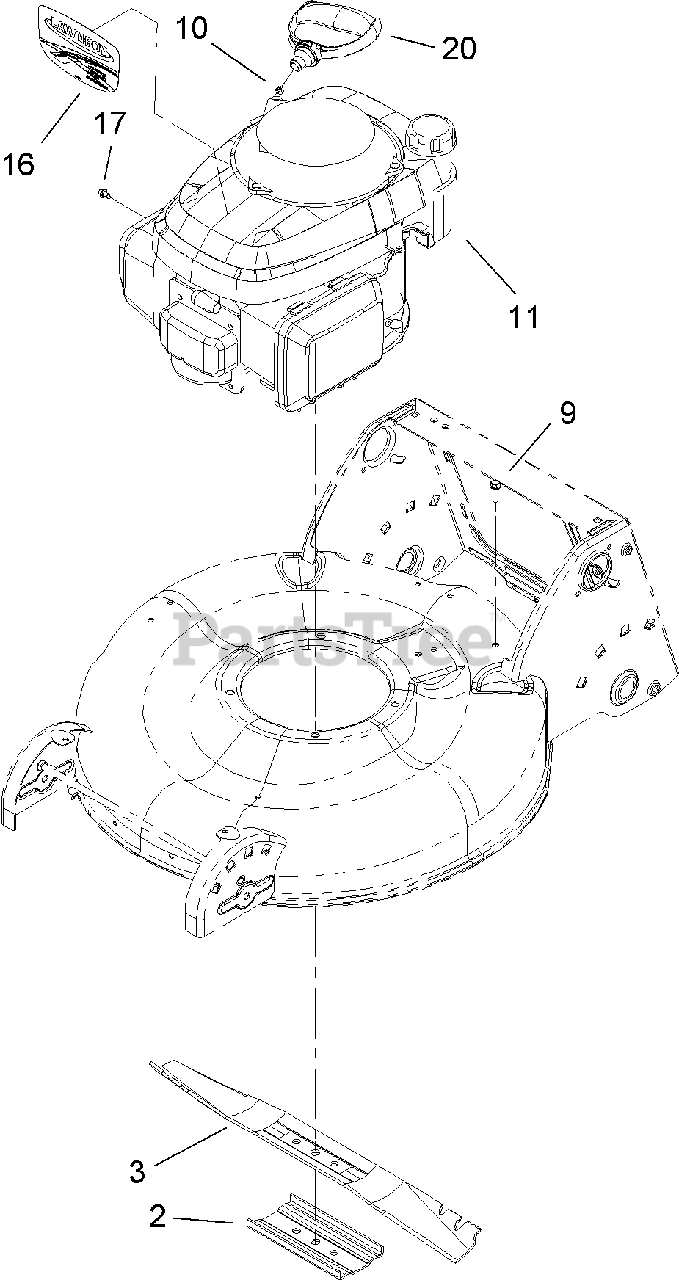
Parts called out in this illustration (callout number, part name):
2	SUPPORT-BLADE
3	BLADE-21 INCH
9	SCREW-HWH
10	STOP-ROPE
17	SCREW-HWH
20	HANDLE-RECOIL
